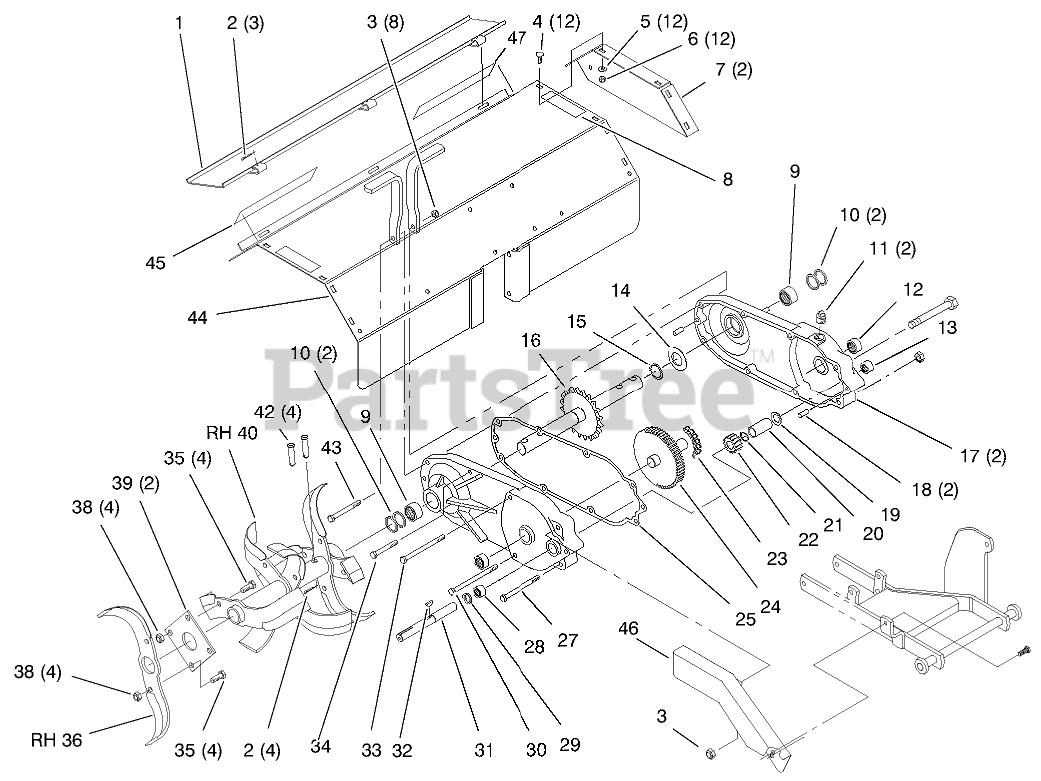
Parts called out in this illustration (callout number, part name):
1	GUARD ASM
2	PIN-COTTER
3	NUT-LOCK, NI
4	BOLT-CARR
5	WASHER-PLAIN
6	NUT-LOCK, NI
7	COVER-TINE END
8	DECAL-DANGER
9	BEARING-NEEDLE
11	PLUG-PIPE, SQH
12	BEARING-NEEDLE
13	BEARING-NEEDLE
14	WASHER
15	RING-RETAINING
16	TINE SHAFT ASM
17	GEAR CASE TILLER RED
18	PIN-ROLL
19	WASHER-THRUST
20	TUBE-SPACER
21	Ring-Snap
22	GEAR-PINION
23	CHAIN
24	GEAR AND SHAFT ASM
25	GASKET-TRANSMISSION
26	SCREW-HH
27	SCREW-HH
28	BEARING-NEEDLE
29	SEAL-OIL
30	SCREW-HH
31	SHAFT-INPUT
32	KEY-WOODRUFF
33	SCREW-HH
34	SCREW-HH
35	SCREW-HH
36	TINE-RH
37	Tine-LH
38	NUT-LOCK, NI
39	PLATE-TINE MTG RED
40	RH TINE ASM
41	LH TINE ASM
42	PIN-CLEVIS
43	SCREW-HH
44	Shield W/Safety Decal
45	DECAL-ATTACHMENT
46	GUARD - TILLER RED
47	DECAL-WORKHORSE
